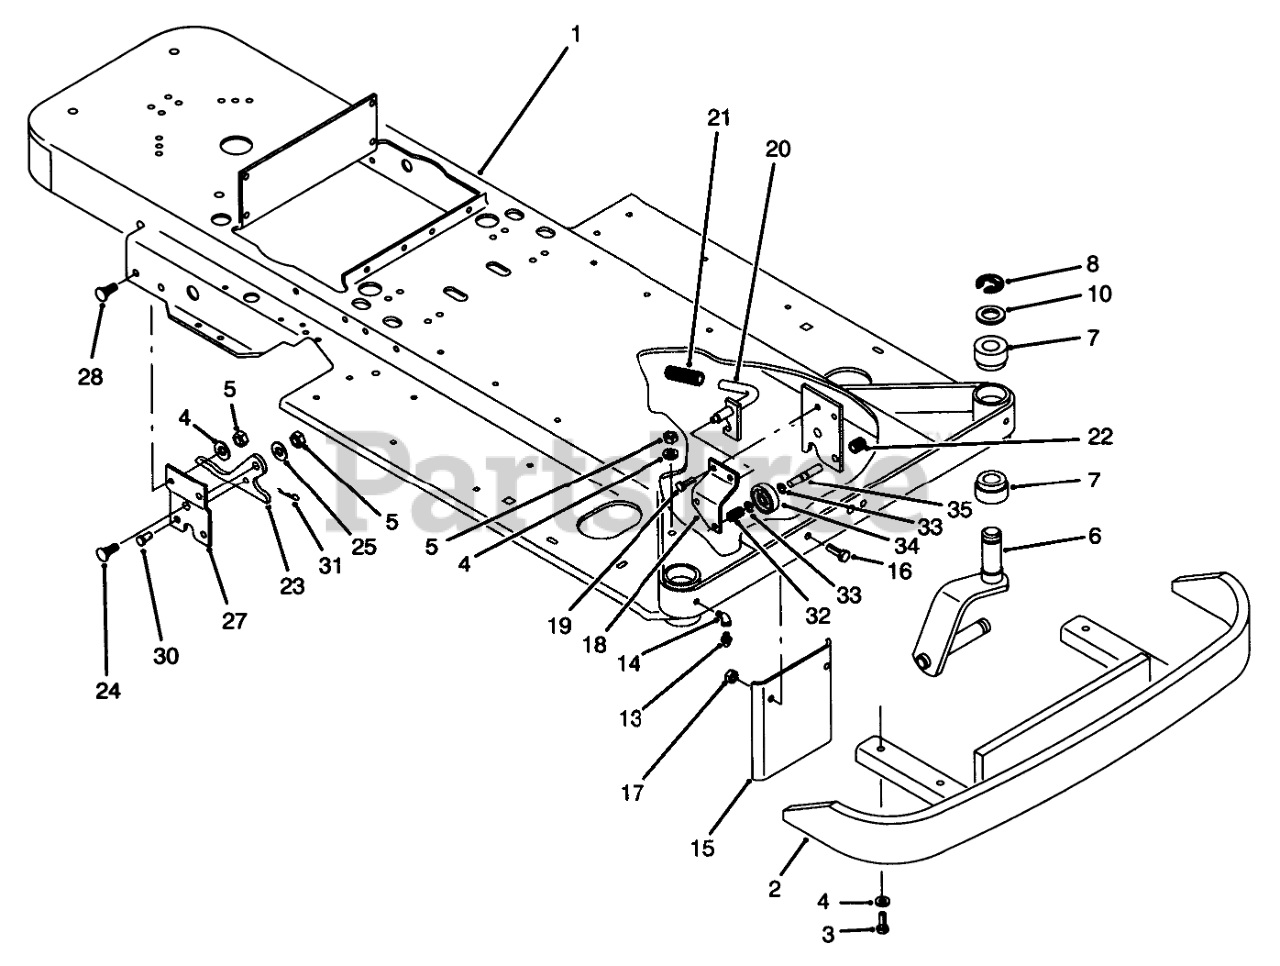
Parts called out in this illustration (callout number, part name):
1	WLDMT-FRAME R
2	Bumper-Front
3	SCREW-HH
4	WASHER-FLAT
5	NUT-LOCK, NI
6	Fork-Front Wheel, LH
7	BUSHING-PIVOT
8	RING-RETAINING
11	Nut
12	DUST CAP
13	FITTING-GREASE
14	ELBOW
15	Shield
16	SCREW-HH
17	NUT-LOCK, NI
18	Bracket LH
19	Screw
20	Latch LH
21	GRIP
22	CAP-ROD, PLUNGER
23	PLATE-LATCHING
24	BOLT-CARR
25	WASHER
27	Plate-Hitch
28	BOLT-CARR
30	Pin
31	Hairpin
32	SPRING
33	RING-RETAINING
35	ROD-LOCK
